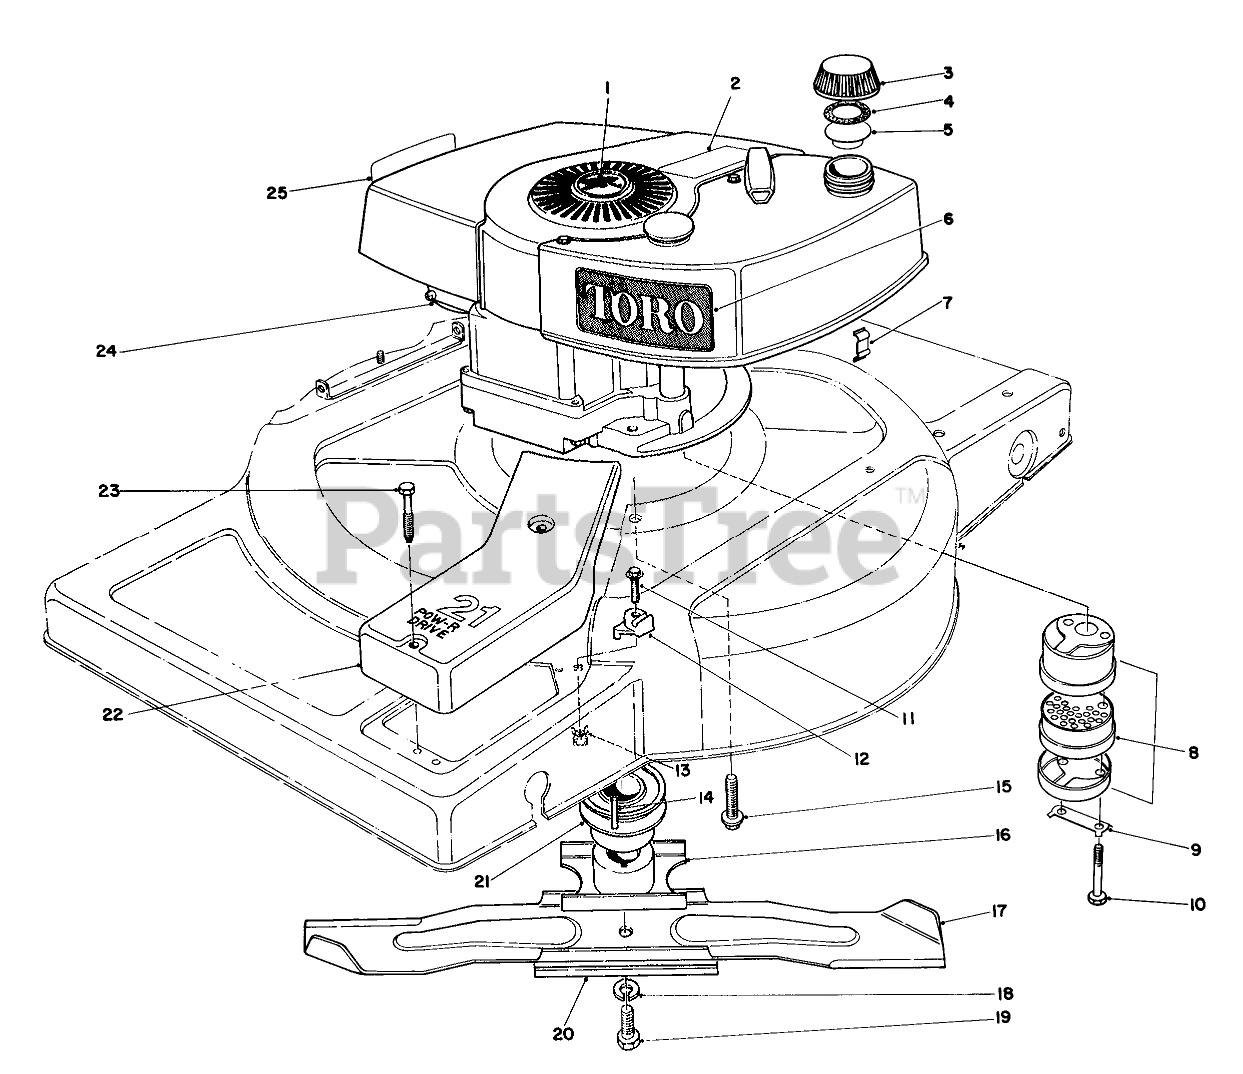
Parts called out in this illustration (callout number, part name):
1	PLUG BUTTON
2	Decal Lockout
3	Gas Cap (Incl. Ref. #4 & 5)
4	GASKET
5	GAS CAP BAFFLE
6	Decal Tow
7	Clip Conduit
8	Muffler Assembly (Incl. Ref. #9 & 10)
9	CLIP - LOCKING
10	SCREW-HH
12	CABLE BOSS
13	SPEED NUT
14	KEY-SQUARE
15	SCREW-HWHTF
16	BLADE RETAINER WA
17	Blade
18	WASHER-LOCK
19	SPECIAL SCREW
20	Stiffener-Blade
21	Pulley
22	COVER BELT
23	SCREW-HHFTF
24	Engine
25	Decal-Maintenan
